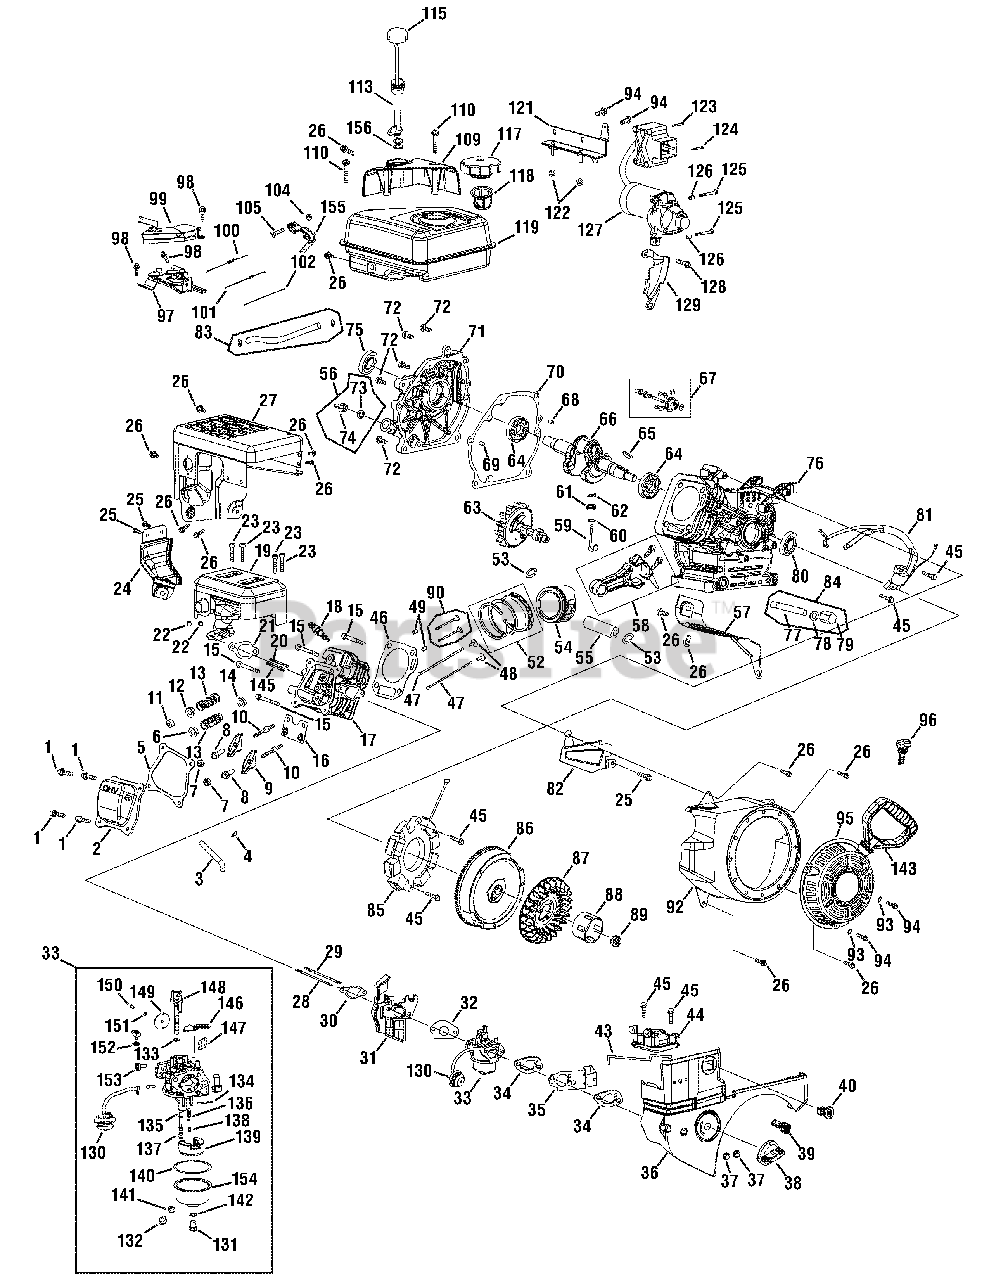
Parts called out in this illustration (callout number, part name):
1	Bolt
2	Valve Cover
3	Breather Hose
4	Hose Clamp
5	Head Cover Gasket
6	Intake Valve Spring Seat
7	Pivot Locking Nut
8	Valve Adjusting Nut
9	Rocker Arm
10	Pivot Bolt
11	Exhaust Valve Adjuster
12	Exhaust Valve Spring Seat
13	Valve Spring
14	Intake Valve Seal
16	Push Rod Guide Plate
17	Cylinder Head - Complete
18	Spark Plug
19	Muffler Assembly
20	Stud
21	Muffler Gasket
23	Bolt
24	Exhaust Pipe Shield
27	Muffler Shroud
28	Stud, M6 x117
29	Stud, M6 x 105
30	Carburetor Insulator Gasket
31	Carburetor Insulator Plate
32	Carburetor Gasket
33	Carburetor Assembly
34	Carburetor Gasket Plate
35	Choke Control Bracket
36	Engine Shroud
38	Choke Knob
39	Throttle Control Knob
40	Ignition Switch
43	Choke Push Rod
44	Heater Box
46	Cylinder Head Gasket
47	Push Rod Kit (incl. intake and exhaust rod)
48	Tappet
49	Dowel Pin
52	Piston Ring Set
53	Piston Pin Snap Ring
54	Piston
55	Piston Pin
56	Oil FIll Plug Assembly
57	Air Shield
58	Connecting Rod Assembly
59	Governor Arm Shaft
60	Washer
61	Governor Seal
62	Cotter Pin
63	Camshaft Assembly
64	Radial Ball Bearing
65	Flywheel Key
66	Crankshaft Assembly
67	Governor Gear/Shaft Assembly
68	Dowel Pin, 7 x 14
69	Dowel Pin, 9 x 14
70	Crankcase Cover Gasket
70	Crankcase Gasket
71	Case Cover
72	Bolt
72	Cover Bolts
73	O-Ring
74	Oil FIll Plug
74	Oil Fill Plug
75	Oil Seal
76	Crankcase
77	Oil Drain Pipe
78	Washer
79	Oil Drain Plug Washer
80	Oil Seal
81	Ignition Coil
82	Air Flow Shield
83	Fuel Line Kit (incl. clamps and fuel line)
84	Oil Drain Assembly, includes 77, 78, 79
85	Stator
87	Cooling Fan
88	Starter Cup
89	Nut
90	Valve Kit (incl. intake and exhaust valve)
90	Valve Kit
92	Blower Housing
93	Washer
95	Recoil Starter Assembly
96	Key
97	Throttle Control Assembly
98	Bolt
99	Governor Shield
100	Governor Spring
101	Throttle Return Spring
102	Governor Rod
105	Bolt
109	Engine/Dipstick Cover
113	Dipstick Tube, incl. Ref. 156
115	Dipstick
117	Fuel Cap Assembly
118	Fuel Filter
119	Fuel Tank
121	Switch Housing Mounting Bracket
122	Nut
123	Bolt, M4 x 55
124	Bolt, M4 x 60
126	Dowel Pin
127	Electric Starter
128	Bolt
129	Blower Housing Shield
130	Primer
131	Bolt
132	Drain Bolt
133	Gasket, Throttle Plate
134	Float Pin
135	Emulsion Tube
136	Needle Valve
137	Main Jet
138	Needle Valve Spring
139	Float
140	Fuel Bowl Gasket
141	Fuel Drain Plug Gasket
142	Fuel Bowl Gasket
143	Starter Handle
145	Muffler Stud Assembly
146	Choke Shaft
147	Choke Plate
148	Throttle Shaft
149	Throttle Plate
150	Screw, M3×5
151	Lock Washer
152	Idle Jet Assembly
153	Idle Speed Adjusting Screw
154	Fuel Bowl
155	Governor Arm Bracket
